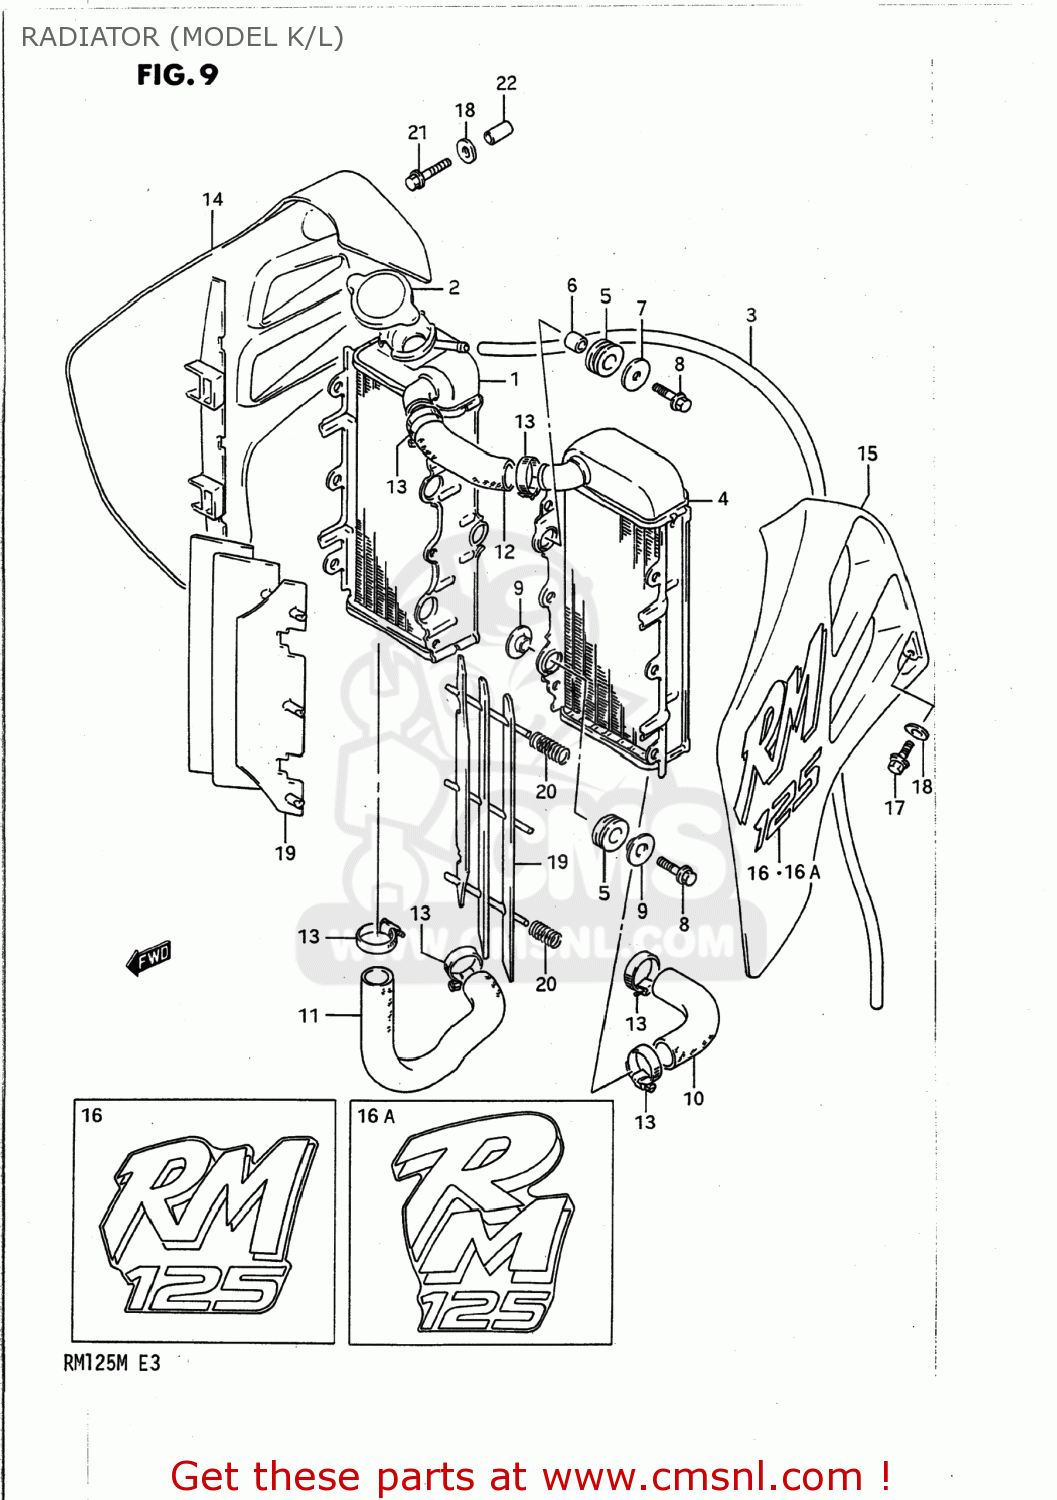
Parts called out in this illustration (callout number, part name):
1	RADIATOR ASSEMBLY,WATER
2	CAP,RADIATOR 1.1
3	HOSE
4	RADIATOR,WATER,L
5	CUSHION,RADIATOR LWR
6	SPACER(6.5X10.5X12)
7	WASHER (6.5X24X1.2)
8	BOLT
9	WASHER,RDTR SPRT
10	HOSE,RADIATOR INLET
11	HOSE,RADIATOR
12	HOSE,RADIATOR
13	CLAMP
14	COVER,RADIATOR,R
15	COVER,RADIATOR,L
16	EMBLEM,RADIATOR COVER
16A	EMBLEM,RADIATOR COVER
17	BOLT
18	GASKET(6.5X20X1.5) (NAS)
19	LOUVER,RADIATOR
20	SPRING
21	BOLT
22	SPACER(6.4X10X22)
